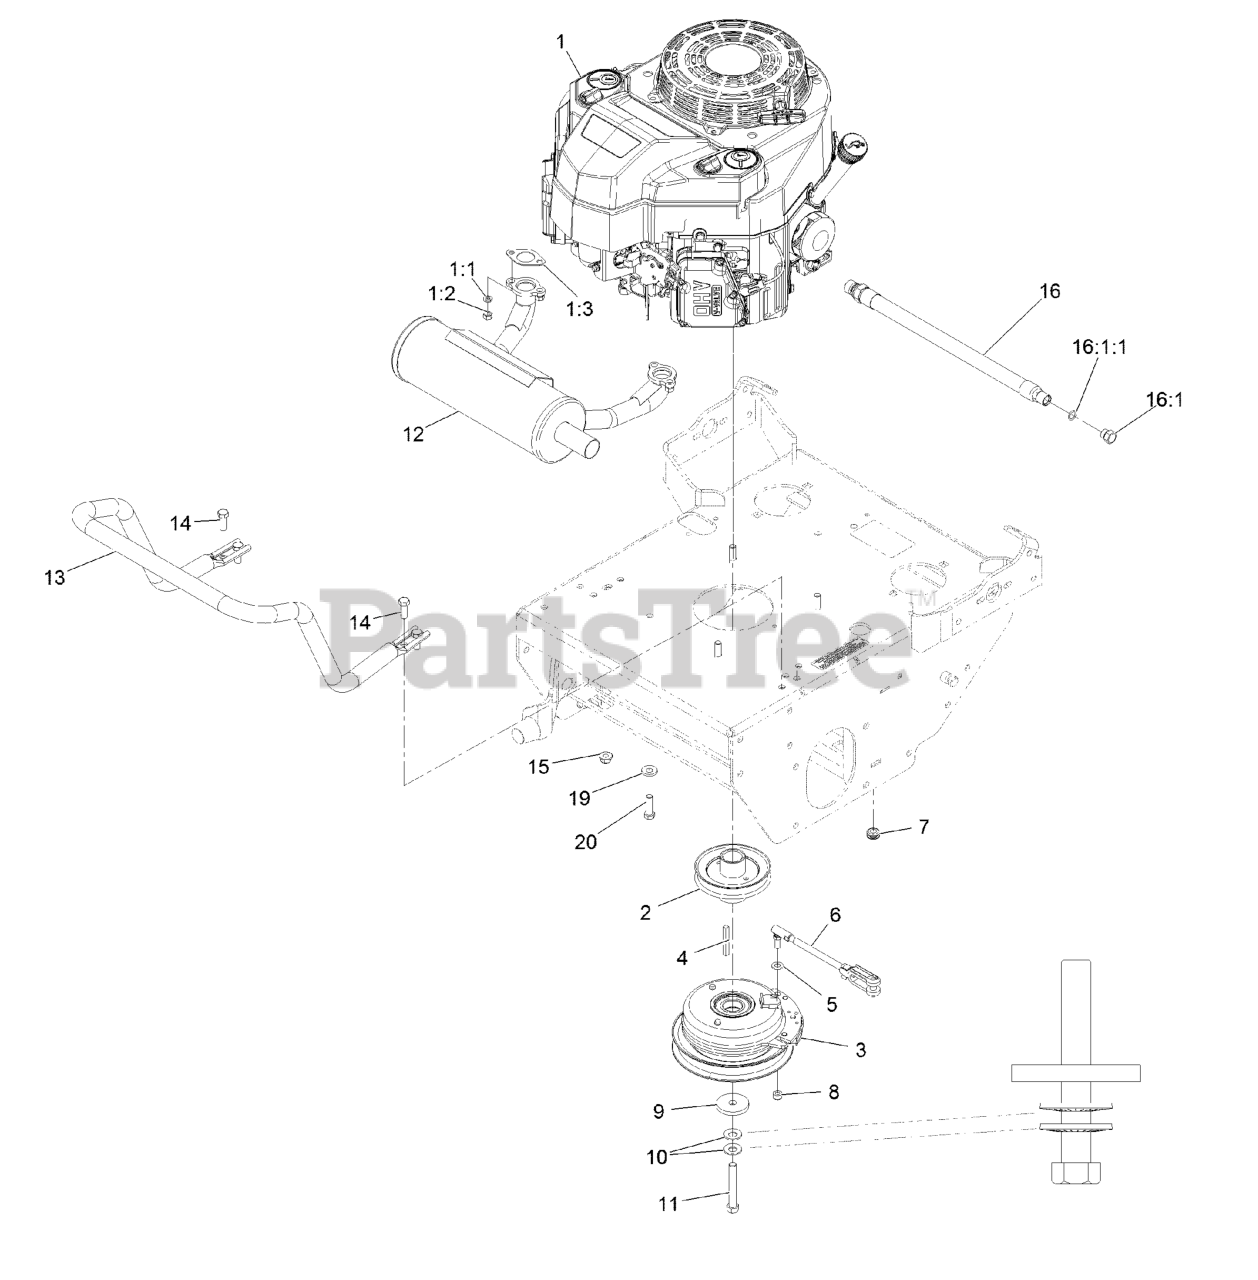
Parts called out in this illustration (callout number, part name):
1:1	WASHER-LOCK
1:3	GASKET-EXHAUST
2	SHEAVE, W/ HUB
3	CLUTCH, 105 FT/LBS, 1.13
4	KEY-SQUARE
5	WASHER-PLAIN
6	ASM, CLUTCH ANCHOR
7	GROMMET
8	NUT-LOCK
9	WASHER-CLUTCH
10	WASHER-SPRING
11	SCREW-HH
12	MUFFLER-HORIZONTAL
13	TUBE-GUARD MUFFLER
14	SCREW-HH
15	NUT-HF, NI
16	ASM, ENGINE OIL DRAIN HOS
16:1	PLUG-HH
16:1:1	O-RING
19	WASHER-BELLEVILLE
20	SCREW-HH
